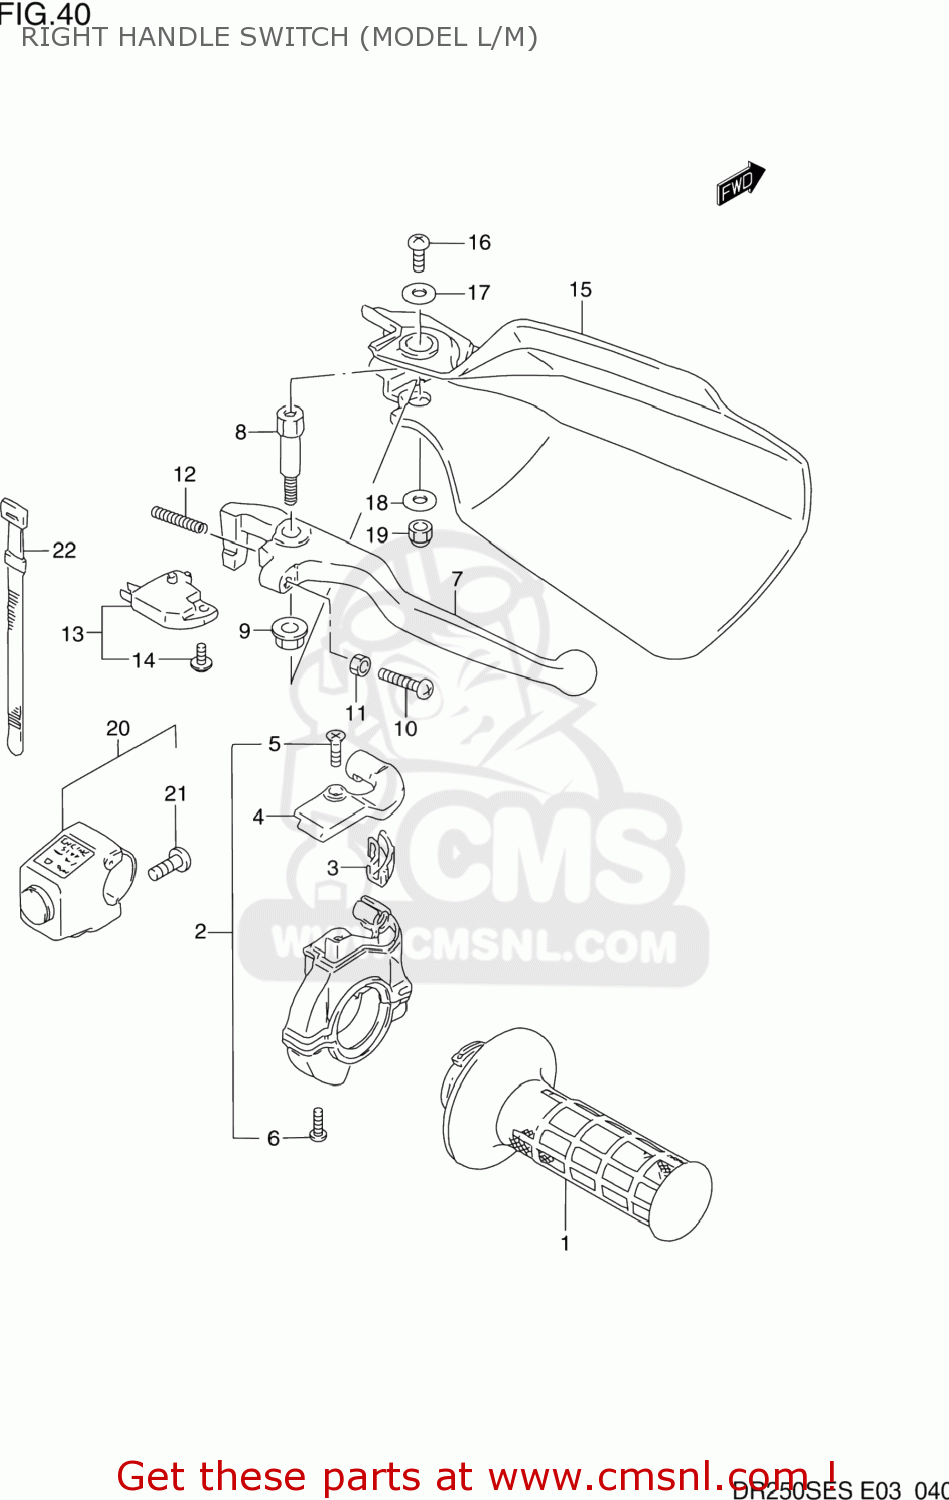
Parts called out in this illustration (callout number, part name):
1	GRIP,THROTTLE
2	CASE ASSEMBLY,THROTTLE
3	GUIDE PIECE,THROTTLE
4	COVER,THROTTLE CASE
5	SCREW 4X10
6	SCREW
7	LEVER,BRAKE
8	BOLT,BRAKE LEVER PIVOT
9	NUT 6MM
10	BOLT,ADJUST
11	NUT ,5MM
12	SPRING,RETURN
13	SWITCH ASSEMBLY,STOP
14	SCREW
15	COVER,KNUCKLE,R
16	SCREW(5X10)
17	WASHER (5.5X16X1.2)
18	WASHER (6.5X17X1.6)
19	NUT 6MM
20	SWITCH ASSEMBLY,HANDLE,RIGHT
21	SCREW
22	CLAMP(L:120)
